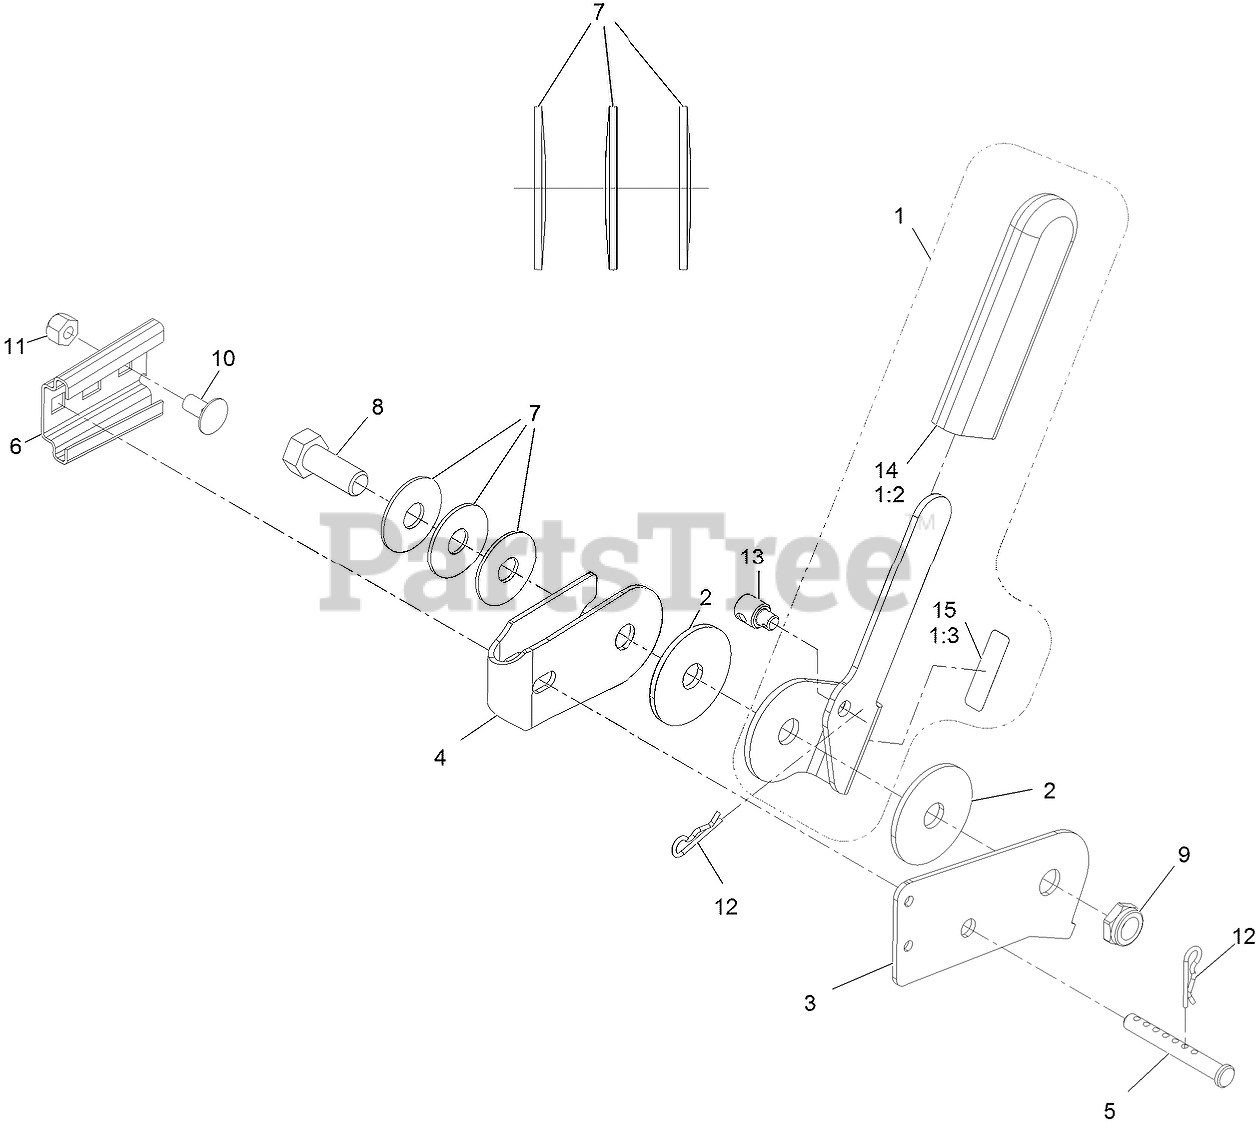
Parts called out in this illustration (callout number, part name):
1	CONTROL HANDLE ASM-OCD
1:2	GRIP-LEVER
1:3	DECAL-OPERATION
2	DISC-FRICTION
3	BRACKET,CONTROL MOUNT
4	BRACKET,HANDLE MOUNT
5	PIN-CLEVIS
6	BRACKET-MOUNTING,SMV
7	WASHER-DISC, SPRING
8	SCREW-HH
9	NUT-HEX
10	SCREW-CARR
11	NUT-LOCK, NI
12	PIN-COTTER
13	PIVOT, CONTROL CABLE
14	GRIP-LEVER
15	DECAL-OPERATION
